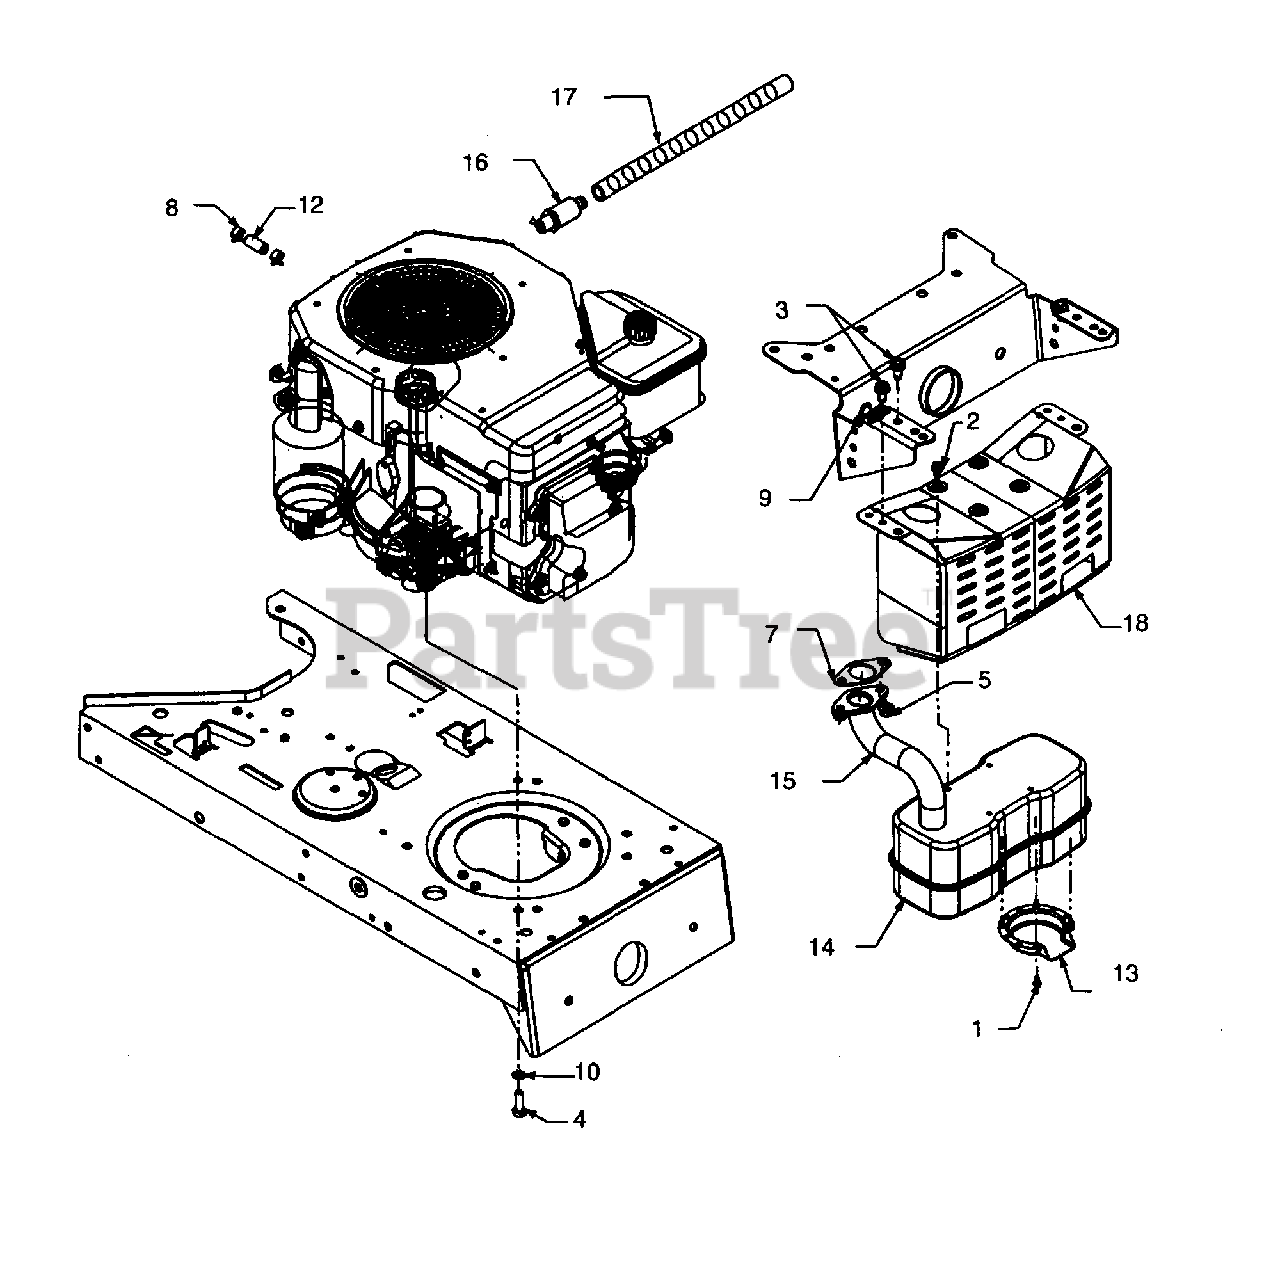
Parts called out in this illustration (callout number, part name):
1	Hex Tap Scr. #8-32 x .38" Lg.
2	Hex Wash. TT-Tap Scr. 1/4-20 x 5" Lg.
3	Hex Wash. TT-Tap Scr. 5/16-18 x .62" Lg.
4	Hex Bolt M8 x 1.25
5	Hex Flange Nut M8 Thd.
7	Exhaust Gasket
8	Hose Clamp
10	External L-Wash. 5/16" I.D.
12	Fuel Line 12" Lg.
13	Muffler Deflector
14	Muffler
15	Exhaust Pipe
16	Oil Drain
17	Oil Drain Hose
